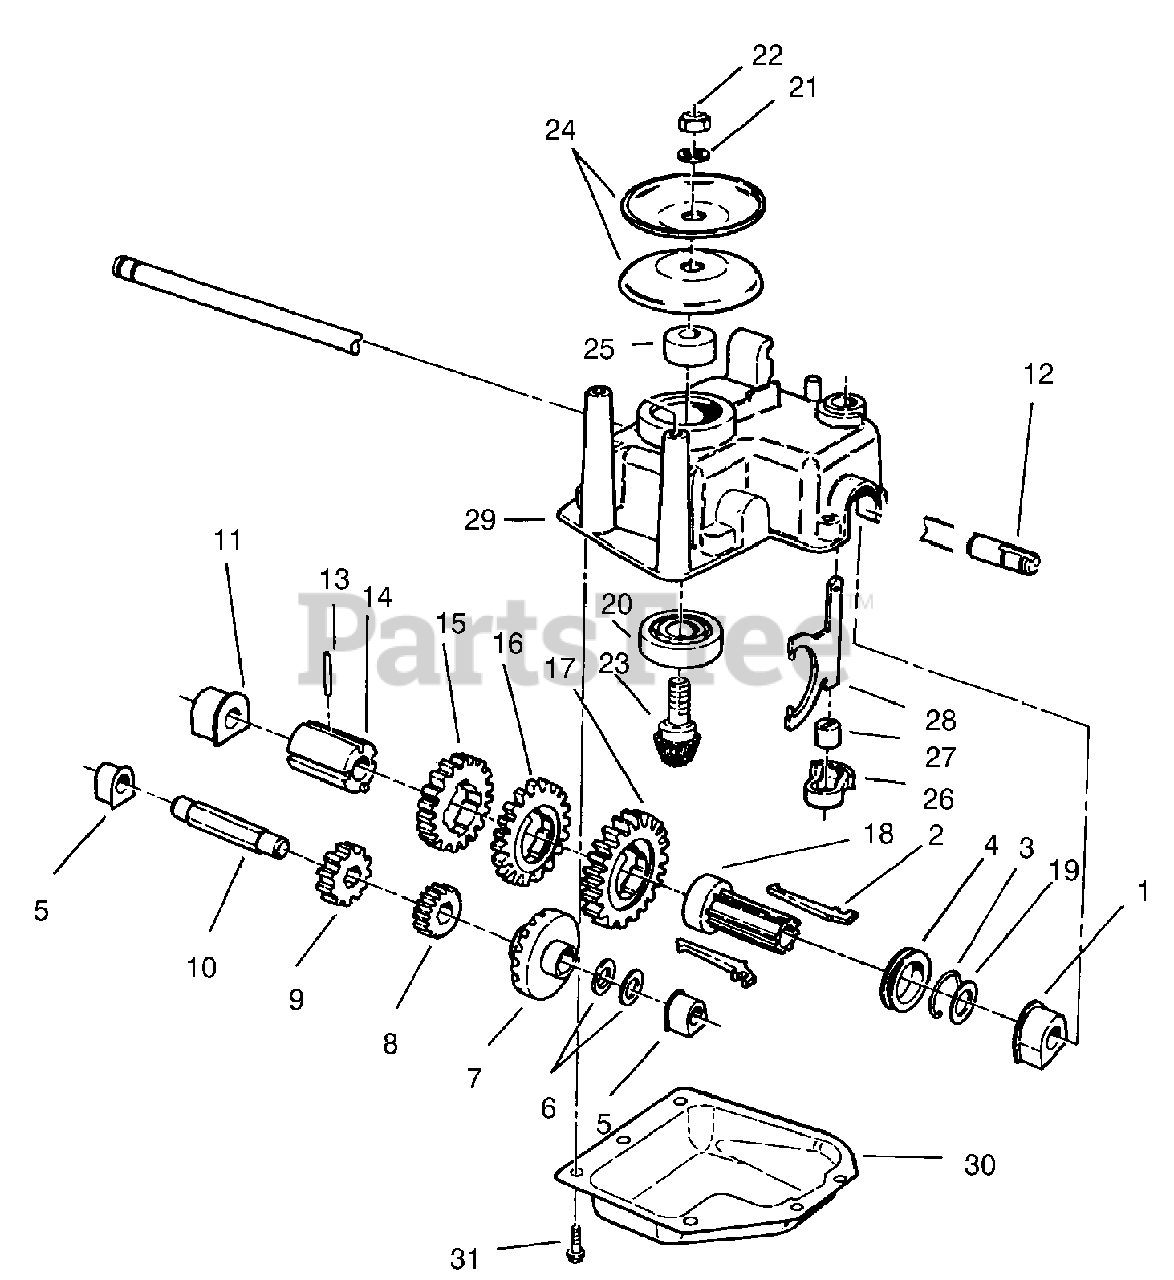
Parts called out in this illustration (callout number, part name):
1	BUSHING-OUTPUT
2	KEY-SHIFT
3	CLIP-SPRING
4	COLLAR-SHIFT
6	WASHER-THRUST
7	GEAR-15T SPUR, 37T BEVEL
8	PINION-20 T
9	PINION-25 T
10	Shaft-Intermedia
12	SHAFT-OUTPUT
13	PIN-GROOVE
14	SLEEVE-GEAR
15	GEAR-39 T
16	GEAR-44 T
17	GEAR-49 T
18	SLEEVE-KEY, SHIFT
20	BEARING-BALL
21	WASHER-FLAT
22	NUT-LOCK, NI
24	PULLEY-HALF
26	RETAINER-FORK, SHIFT
27	BUSHING-YOKE
28	YOKE-SHIFT
29	CASE-GEAR, UPPER
30	COVER-CASE, GEAR
31	SCREW-TAPPING
